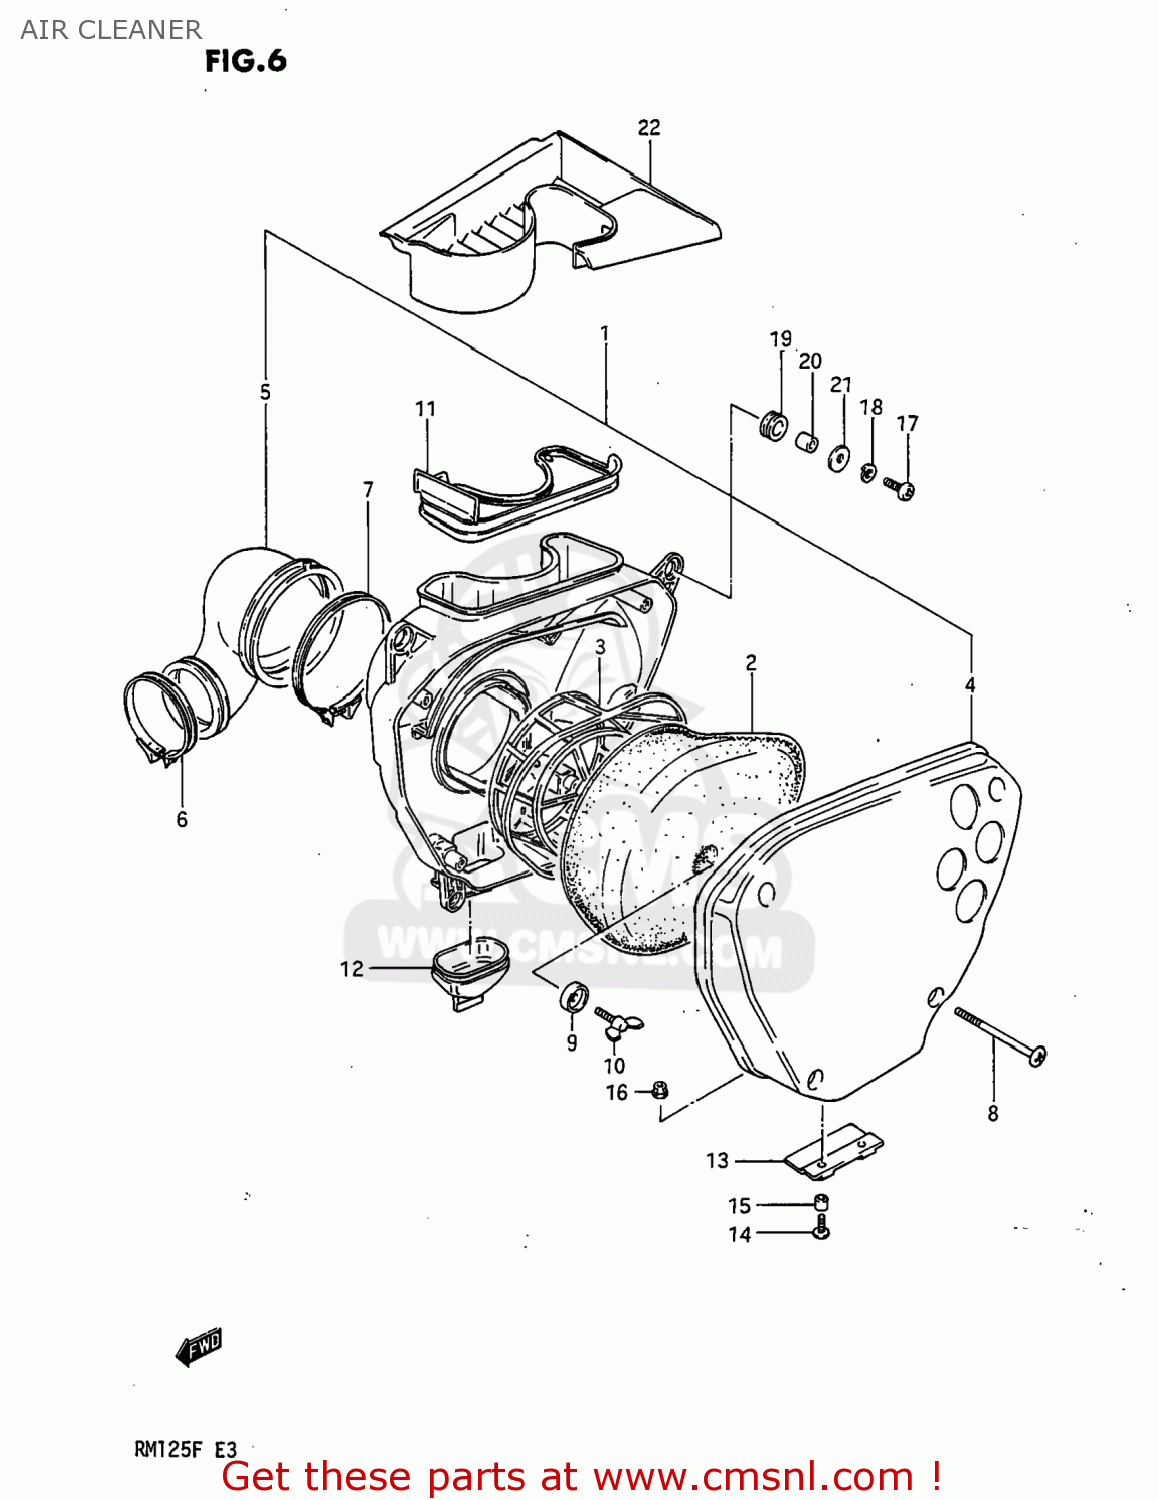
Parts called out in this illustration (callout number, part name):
1	CLEANER ASSEMBLY,AIR
2	FILTER,AIR CLEANER
3	HOLDER,AIR CLEANER
4	CAP,AIR CLEANER
5	TUBE,AIR CLEANER OUTLET
6	CLAMP
7	CLAMP
8	SCREW
9	WASHER,FILTER HOLDER
10	BOLT,AIR CLEANER
11	GUARD,MUD
12	TUBE,DRAIN
13	SHEET,AIR CLEANER
14	SCREW
15	COLLAR
16	NUT
17	SCREW
18	LOCK WASHER
19	CUSHION
20	SPACER (7X9X7)
21	WASHER
22	GUIDE,AIR CLEANER NO.2 MU
